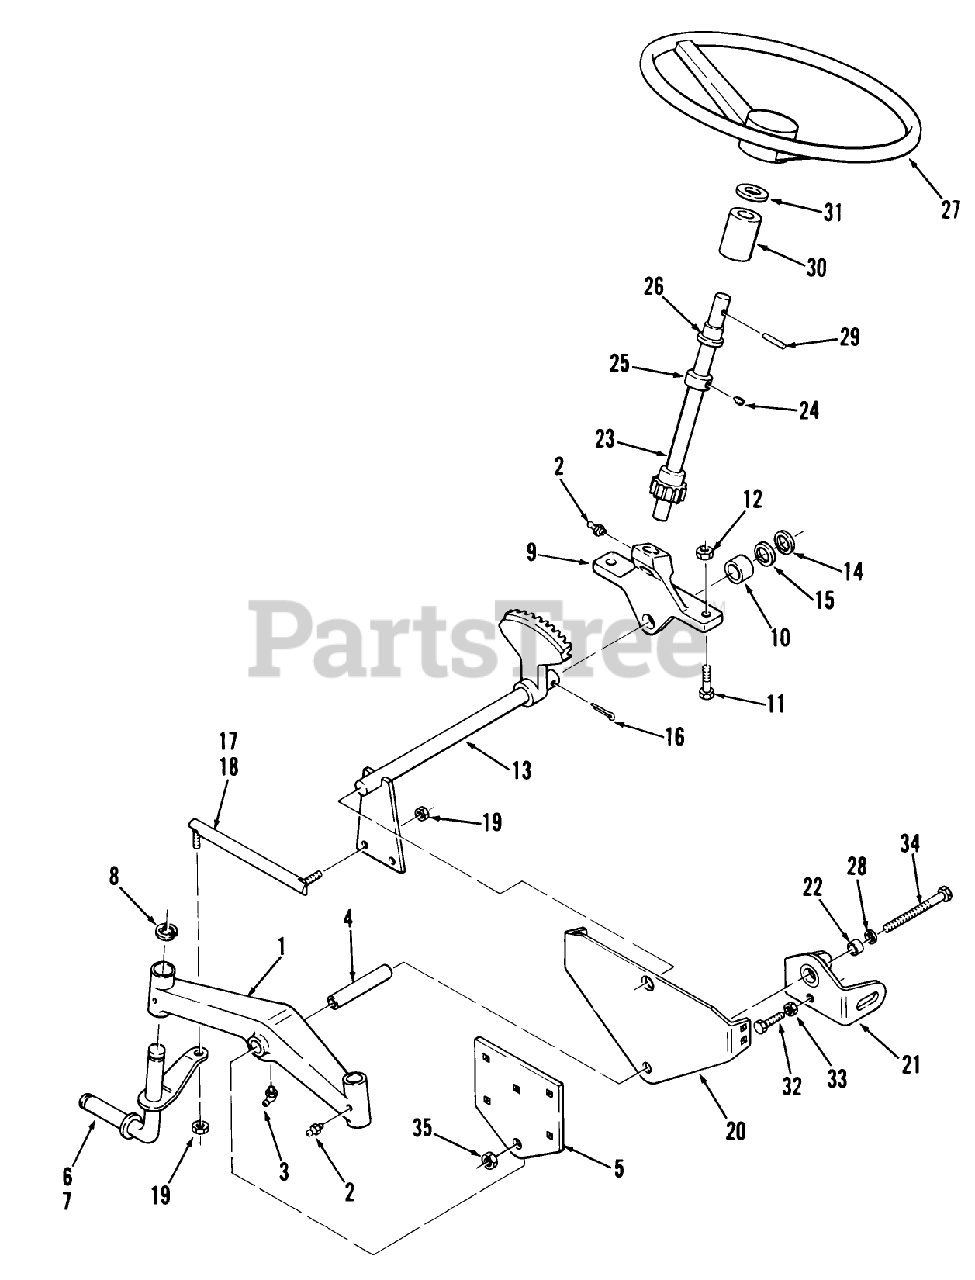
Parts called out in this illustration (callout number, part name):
3	FITTING-GREASE
10	BEARING-BRONZE
14	WASHER-SHIM
15	WASHER
26	BEARING
31	WASHER-BOWED
